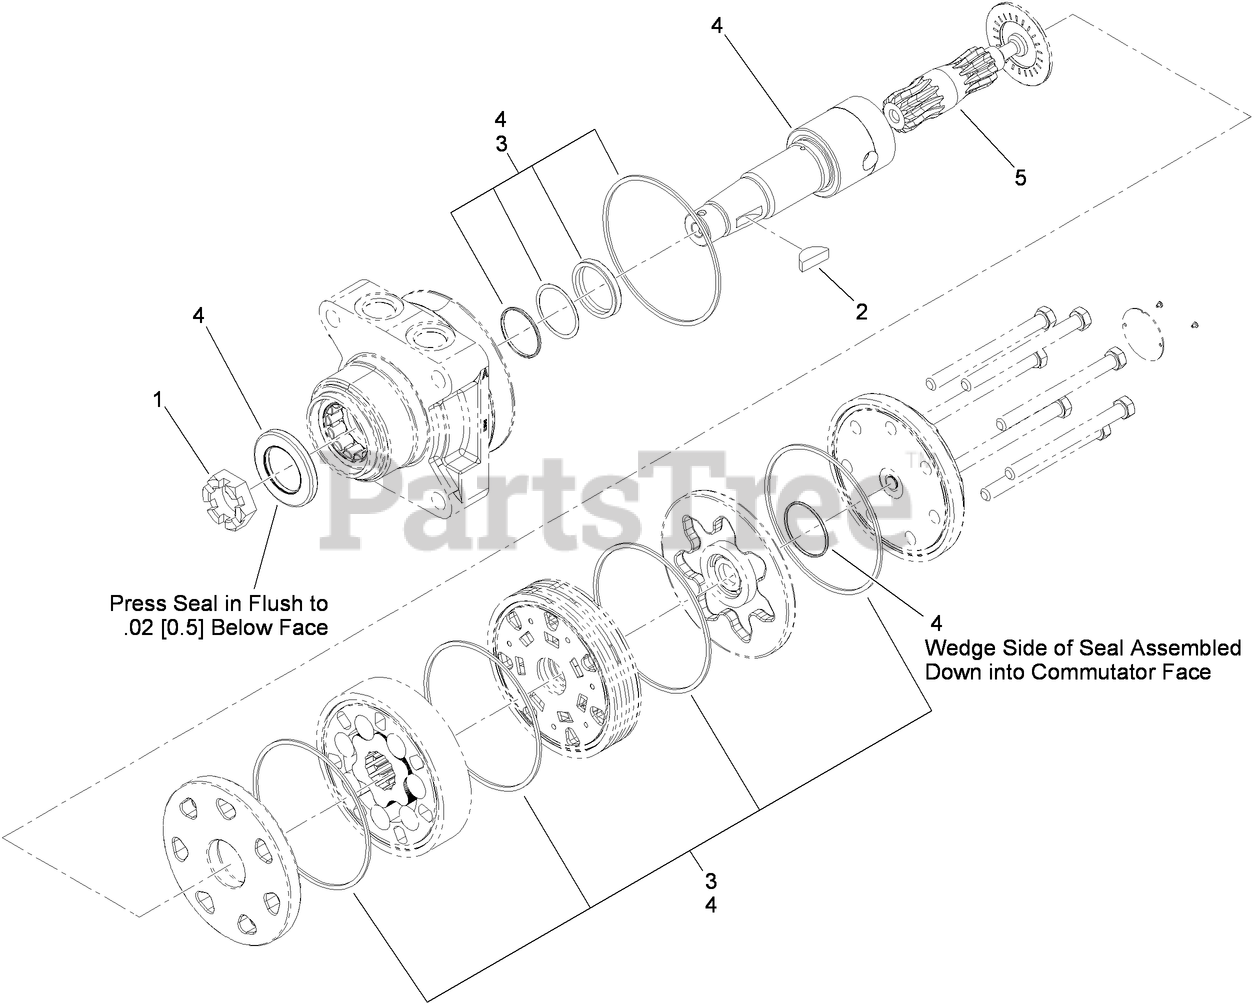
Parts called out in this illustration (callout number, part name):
1	NUT-HH
2	KEY-WOODRUFF
3	SEAL KIT
4	OUTPUT SHAFT and SEALS KIT
5	Drive Link Kit
